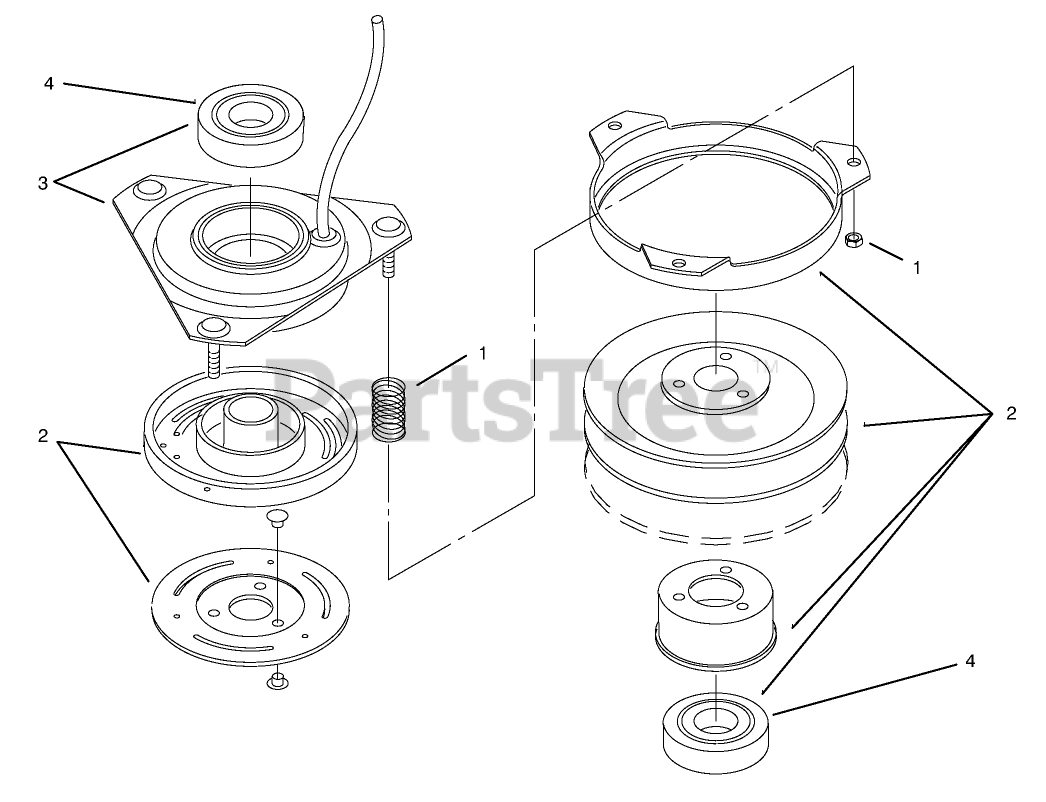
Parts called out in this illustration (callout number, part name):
1	ACCESSORY PKG SRVC PART
2	ROTOR & ARMATURE ASSY
3	FIELD ASSY (SRVC PART)
4	BEARING-ELEC CLUTCH
